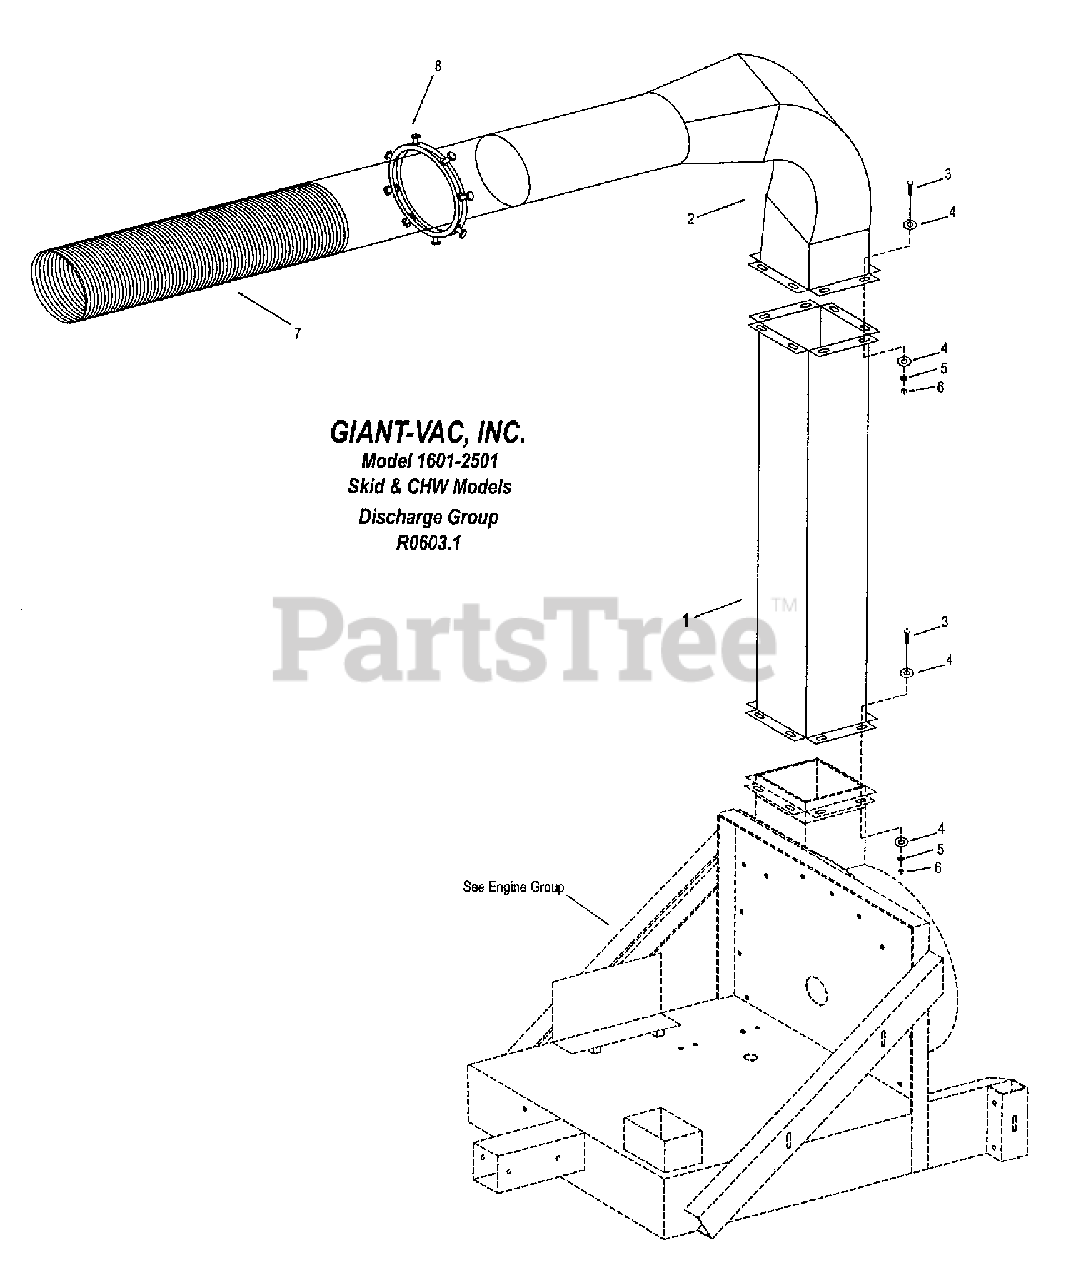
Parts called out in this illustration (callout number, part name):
1	Discharge stack
2	Discharge elbow
3	Bolt, hex -3/8-16 x 1-1/4"
4	Washer, flat -3/8"
5	Washer, lock-3/8"
6	Nut, hex -3/8-16
7	Hose, discharge -8" x 5' metal
8	Ring, squeeze -8"
